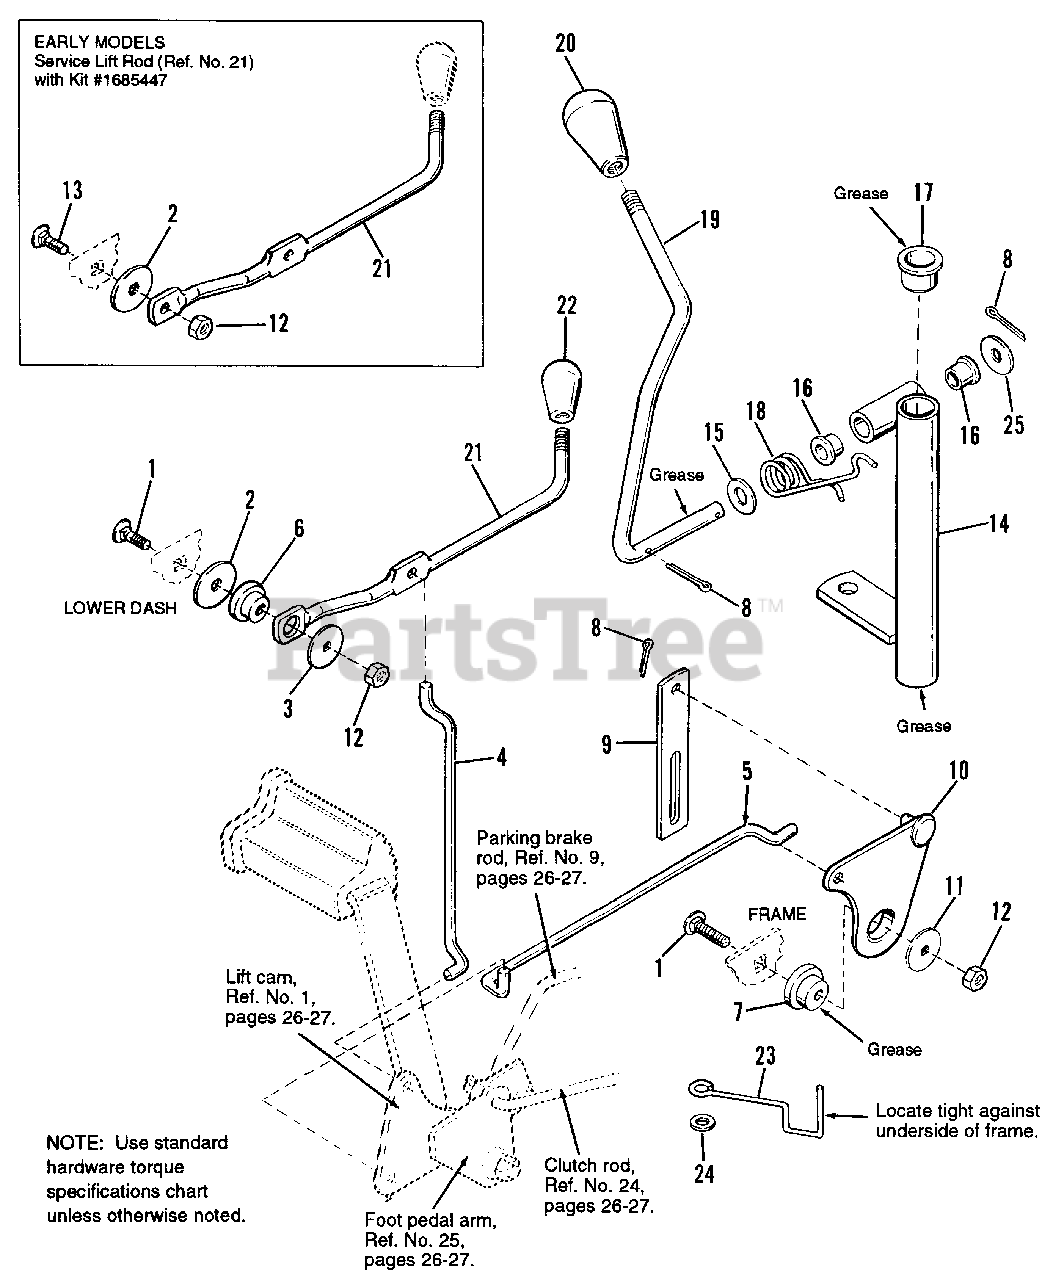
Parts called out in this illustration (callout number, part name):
1	CARRIAGE BOLT, 5/16-18 x 1-1/2 (Later models only)
2	WASHER, Plain, 13/32 x 1-1/2 x 1/8
3	WASHER
4	LINK, Lift Upper
6	SPACER, Special
7	SPACER, Special
8	COTTER PIN
9	LINK, Lift, Upper Transport
10	CAM, Lift Assy.
11	WASHER, Plain, 21/64 x 1-1/4
12	NUT, Hex ESNA Lock, 5/16-18
13	CARRIAGE BOLT, 5/16-18 x 1 (Early models only)
14	SHIFT LEVER ASSY.
15	WASHER, Plain
16	BUSHING, Plastic, 1/2 Dia.
17	BUSHING, Nylon, 3/4 Dia.
18	SPRING, Torsion
19	LEVER, Shift
20	KNOB, Plastic
21	ROD, Lift Handle Kit (Early models)
21	ROD, Lift Handle (Later Models)
22	KNOB
23	BELT STOP
24	WASHER, Plain
25	WASHER, 1/2
